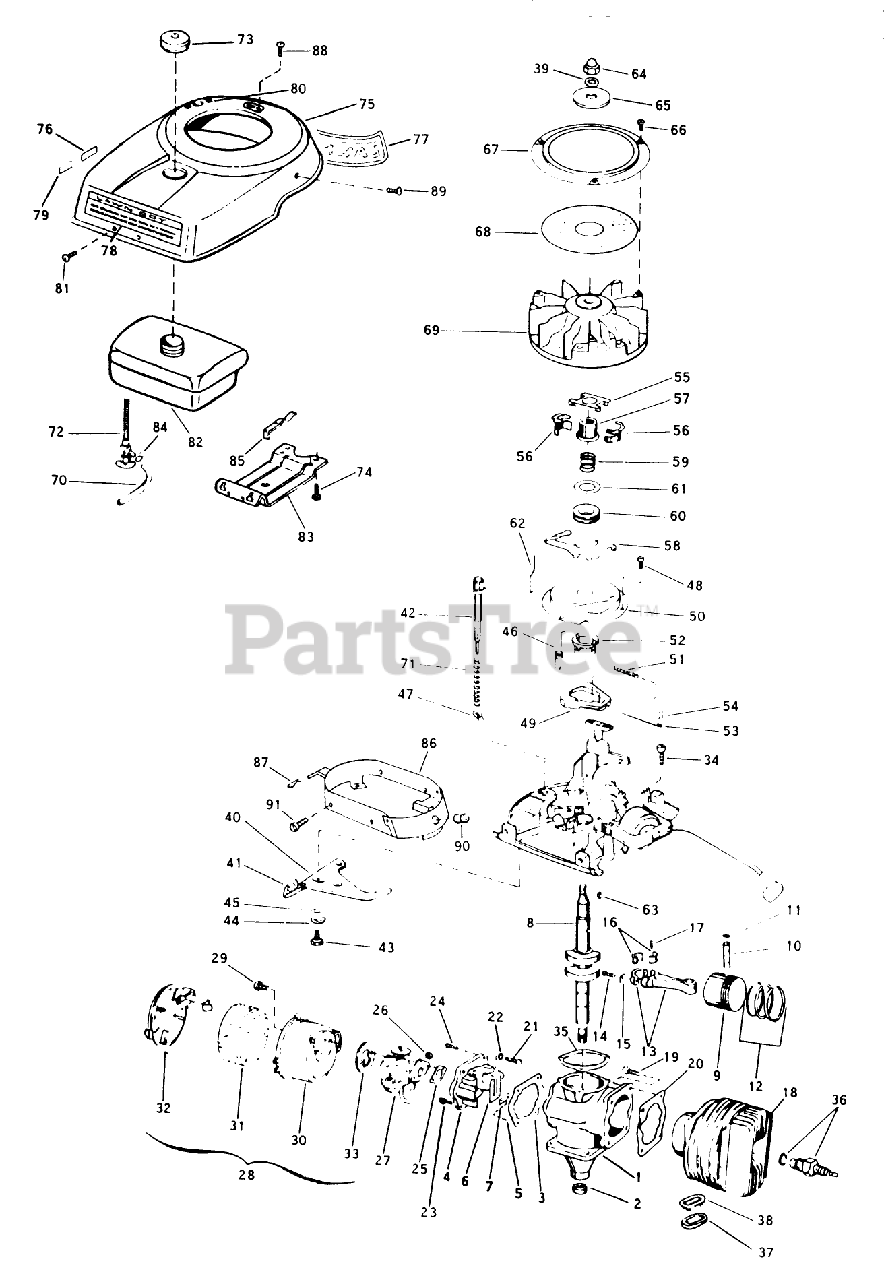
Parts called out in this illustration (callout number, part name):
7	PLATE-BACKUP, REED
11	RING-RETAINING
16	LINER ASM
20	GASKET S
23	SCREW S
24	SCREW S
25	GASKET S
26	STOP NUT
29	SCREW S
31	AIR FIL.ELEM S
35	GASKET S
36	Spark Plug
37	GASKET S
48	SCREW S
49	FLYWEIGHT S
50	DUST COVER S
51	SPARK ADV. SPRING S
52	SPARK ADV. S
53	PIN,SPARK ADV. S
54	SPARK ADJ. SPRING
57	COLLAR S
58	LEVER-GOVERNOR S
59	SPRING S
60	THRUST COLLAR S
67	Ring-Flywhl. Scrn.
70	GAS LINE
71	SPRING S
72	VALVE&SCREEN SM
74	SCREW S
84	CLAMP - HOSE S
89	SCREW S
90	NUT-CLIP
91	SCREW S
